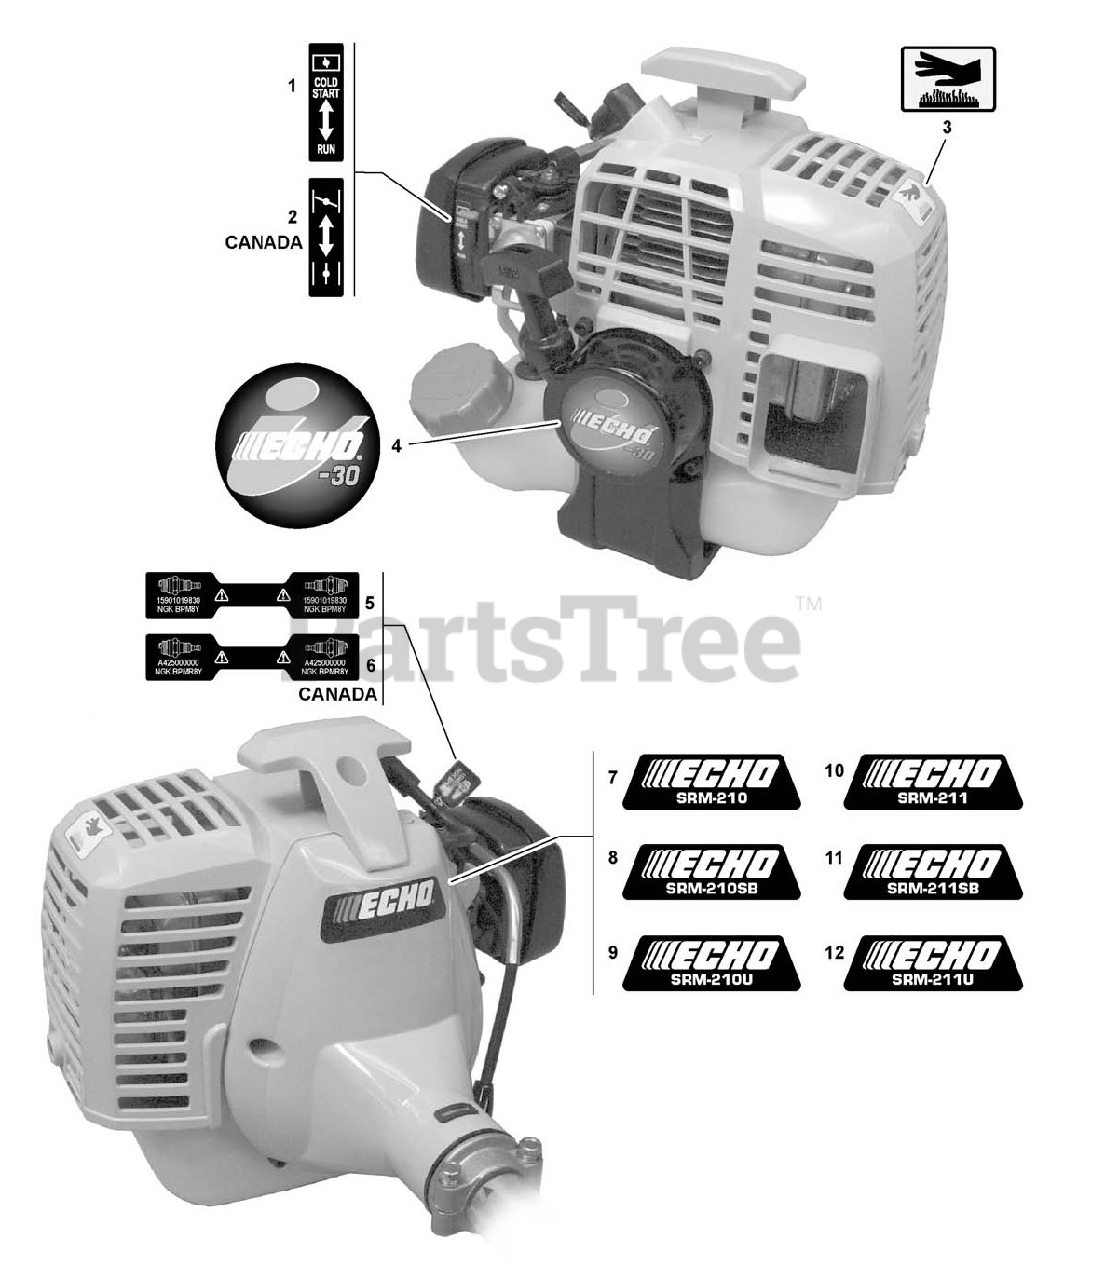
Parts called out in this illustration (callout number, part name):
1	Label - Choke
2	Label - Choke
3	Label - Caution - Hot
4	Label - Echo
5	Label - Spark Plug - BPM-8Y
6	Label - Spark Plug - BPMR-8Y
7	Label - Model - SRM-210
8	Label - Model - SRM-210SB
9	Label - Model - SRM-210U
10	Label - Model - SRM-211
11	Label - Model - SRM-211SB
12	Label - Model - SRM-211U
